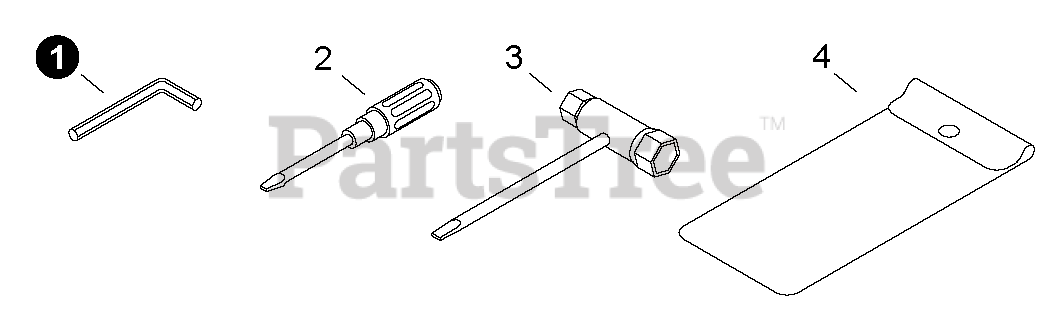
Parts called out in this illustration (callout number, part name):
1	WRENCH, ALLEN 4 MM
2	SCREWDRIVER, PHILLIPS
3	T-WRENCH 13×19 L= 180
4	BAG, TOOL
